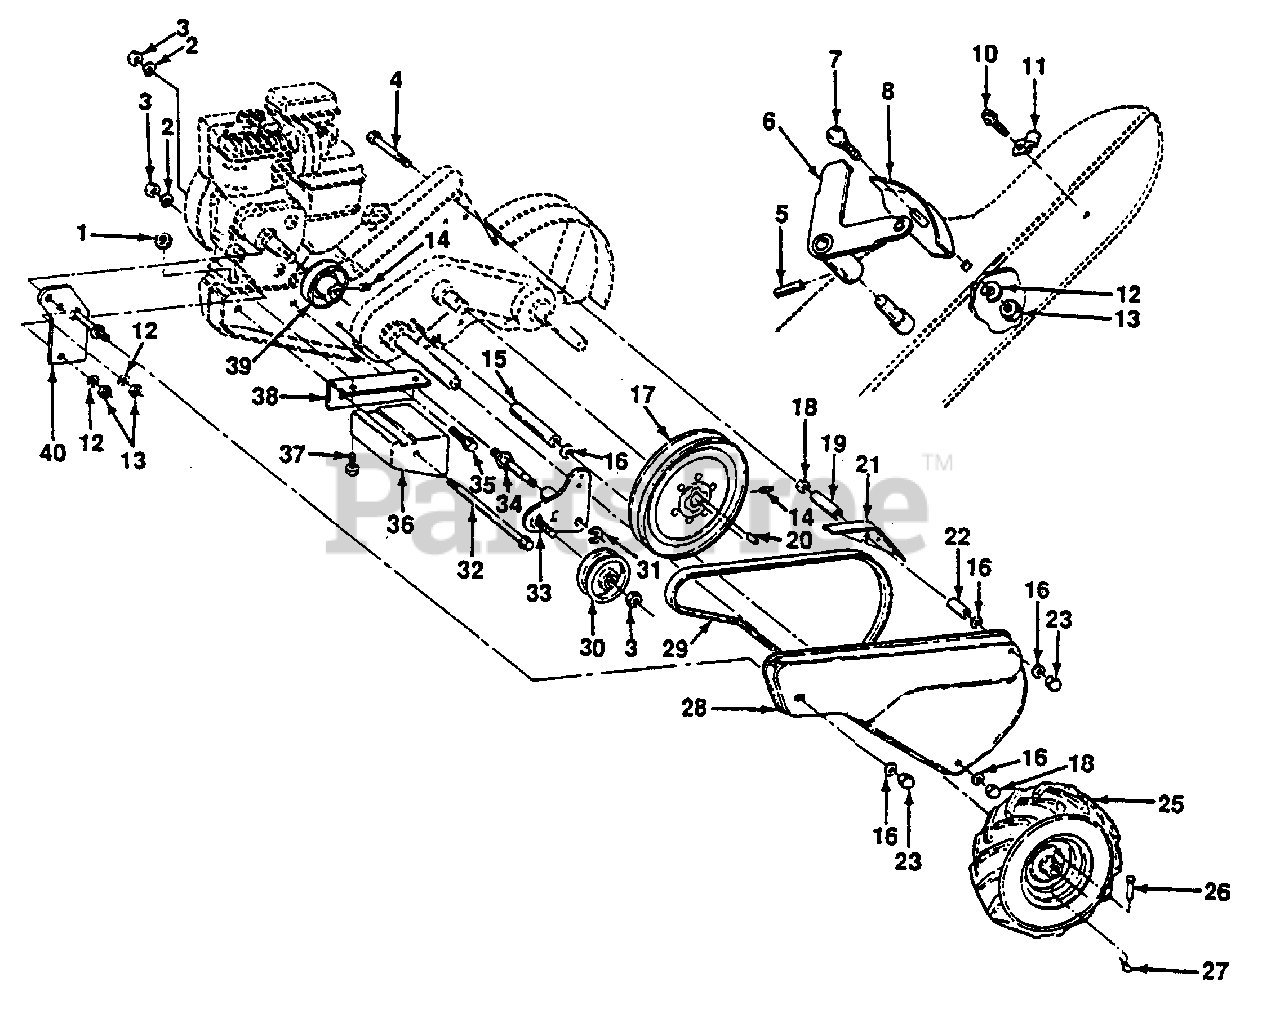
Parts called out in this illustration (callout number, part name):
1	Nut, Keps 5/16-18 (AYP part number)
2	Washer, Lock 3/8 (AYP part number)
3	Nut, Hex 3/8-16 (AYP part number)
4	Bolt, Hex 5/16-18 x 4-3/4 (AYP part number)
5	Pin, Roll (AYP part number)
6	Lever, Shift
7	Bolt Carriage 1/4-20 x 1/2 Gr. 5 (AYP part number)
8	Panel, Shift Indicator (AYP part number)
10	Screw, Hex, Washer Head, Slotted #10-24 x 1/2 (AYP part number)
11	Clip (AYP part number)
12	Washer, Lock 1/4 (AYP part number)
13	Nut, Hex 1/4-20 (AYP part number)
14	Screw, Set Hex 5/16-18 x 3/8 (AYP part number)
15	Spacer, Split 0.327 x 0.42 x 2.68 (AYP part number)
16	Washer 11/32 x 11/16 x 16 Ga. (AYP part number)
17	Sheave, Transmission (AYP part number)
18	Nut, Hex 5/16-18 (AYP part number)
19	Spacer, Split 0.327 x 0.42 x 1.75 (AYP part number)
20	Key, Square 3/16 x 1-1/8 (AYP part number)
21	Guard, Pinch Point (AYP part number)
22	Spacer, Split 0.327 x 0.42 x 2.09 (AYP part number)
23	Nut, Cap 5/16-18 (AYP part number)
25	Tire (AYP part number)
26	Rivet, Drilled (AYP part number)
27	Clip, Hairpin (AYP part number)
28	Guard, Belt (AYP part number)
29	Belt, V (AYP part number)
30	Pulley, Idler (AYP part number)
31	Ring, Klip (AYP part number)
32	Bolt, Hex 5/16-16 x 12 (AYP part number)
33	Bracket, Idler (AYP part number)
34	Shaft, Idler Arm (AYP part number)
35	Bolt, Hex 3/8-16 x 1 (AYP part number)
36	Counterweight, L. H. (AYP part number)
37	Bolt, Hex 5/16-18 x 1-1/2 (AYP part number)
38	Bracket, Reinforcement, L.H. (AYP part number)
39	Sheave, Engine (AYP part number)
40	Bracket, Guard, Belt (AYP part number)
